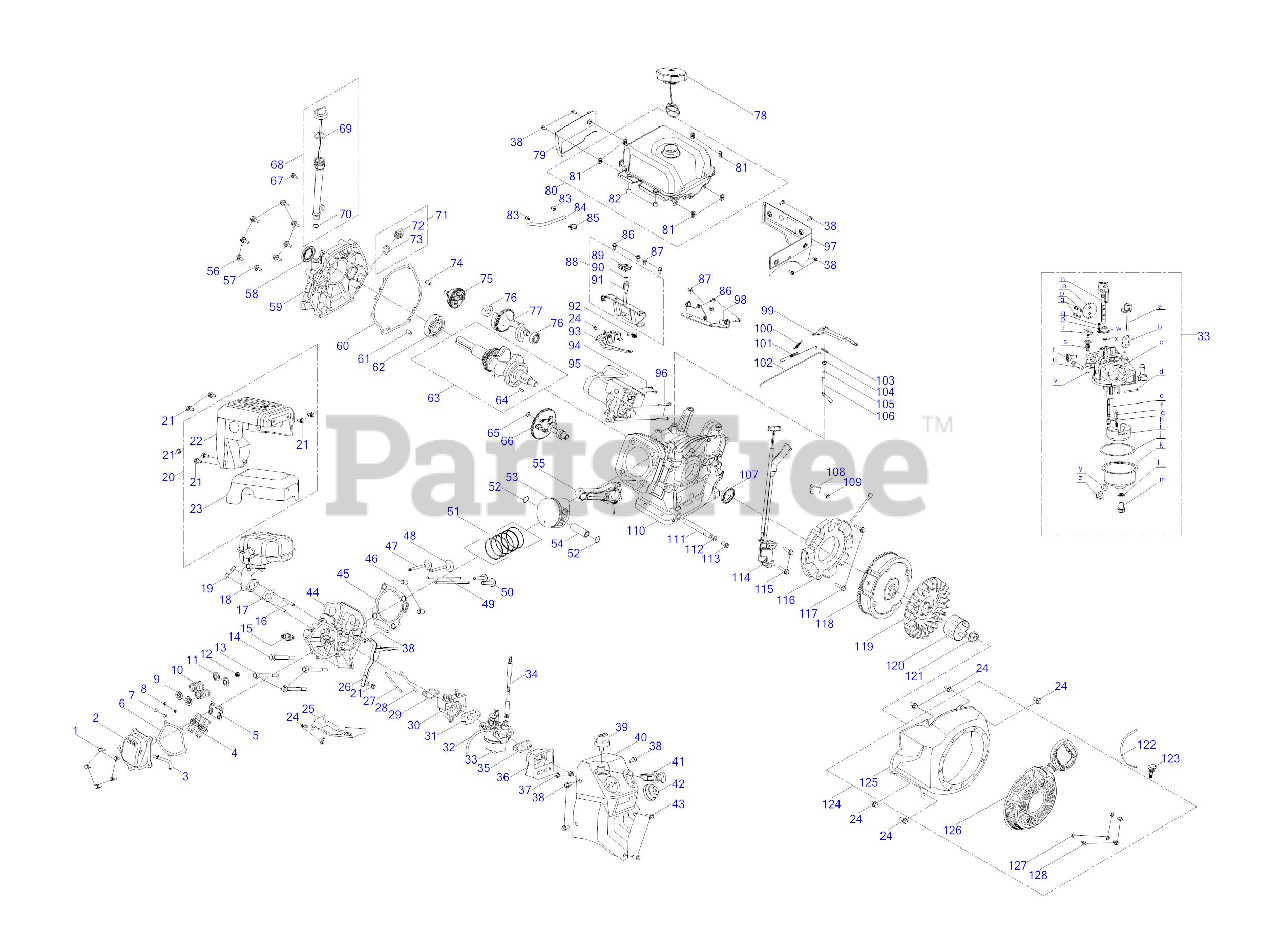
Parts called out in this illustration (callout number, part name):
1	Bolt, M6X16
2	Valve Cover
3	Breather Hose
4	Rocker Arm Assembly
5	Rocker Arm Base
6	Gasket, Valve Cover
7	Valve Adjust Cap, Exhaust
8	Valve Locker
9	Valve Spring Seat
10	Valve Spring
11	Valve Spring Seat
12	Intake Valve Seal
13	Bolt, M10X1.25X87
14	Bolt, M10X1.25X65
15	Spark Plug
16	Stud, M8X48.5
17	Gasket, Muffler
18	Muffler
19	Nut, M8
20	Muffler Guard
21	Bolt, M6X10
22	Muffler Shroud
23	Muffler Inner Shield
24	Bolt, M6X12
25	Shroud
26	Snow Guard
27	Stud, M6-8X108
28	Stud, M6-8X126
29	Gasket, Carburetor Insulator
30	Insulator
31	Carburetor Gasket
32	Fuel Hose, 3.2X6.5X170
33	Carburetor
34	Choke Linkage
35	Gasket, Air Filter
36	Heater Box
37	Nut, M6
38	Bolt, M6X14
39	Choke Lever
40	Control Panel
41	Stop Switch
43	Bolt, M6X20
44	Cylinder Head
45	Gasket, Cylinder Head
46	Pin, 12X20
47	Exhaust Valve
48	Intake Vavle
49	Push Rod
50	Tappet
51	Piston Ring Set
52	Circlip
53	Piston
54	Piston Pin
55	Connecting Rod Assembly
56	Bolt, M8X38
57	Bolt, M8X45
58	Oil Seal, 35X52X7
59	Crankcase Cover
60	Gasket, Crankcase
61	Pin, 9X12
62	Bearing, 6207
63	Crankshaft
64	Woodruff Key
65	Washer, 16.2X0.3X24
66	Camshaft
67	Bolt, M6X18
68	Dipstick
69	O-Ring, 21X2.77
70	O-Ring, 13.5X2.5
71	Oil Plug
72	Oil Plug
73	O-Ring, 16X3
74	Pin, 7X14
75	Governor Gear
76	Bearing, 6202
77	Balance Shaft
78	Fuel Cap
79	Decorative Sheet, Right
80	Fuel Tank
81	Fuel Tank Mount Thread Tab
82	Bush, 10X14X14
83	Clamp
84	Fuel Hose, 6.3X12.5X255
85	Clip
86	Bolt, M8X28
87	Bolt, M8X14
88	Front Bracket, Fuel Tank
89	Rubber Grommet
90	Retaining Ring, 10
91	Front Bracket, Fuel Tank
92	Throttle Lever Knob
93	Governor Gear Bracket Assembly
94	Screw, M4X48
95	Electric Starter
96	Bolt, M8X55
97	Decorative Sheet, Left
98	Fuel Tank Base
99	Governor Lever
100	Governor Spring
101	Idle Spring
102	Throttle Linkage
103	Cotter Pin
104	Oil Seal, 8X14X4
105	Washer, 8X0.8X20
106	Governor Gear Shaft
107	Oil Seal, 35X52X7
108	Wire Board
109	Bolt, M6X8
110	Crankcase
111	Oil Drain Pipe
112	Washer, 10X1.5X16
113	Earth Bolt
114	Ignition Module
115	Bolt, M6X28
116	Charging Coil
117	Bolt, M6X30
118	Flywheel
119	Cooling Fan
120	Starter Cup
121	Nut, M16X1.5
122	Tape, L=150mm
123	Stop Switch Key
124	Recoil Starter
125	Blower Housing
126	Recoil Starter
127	Washer, 6
128	Bolt, M6X10
